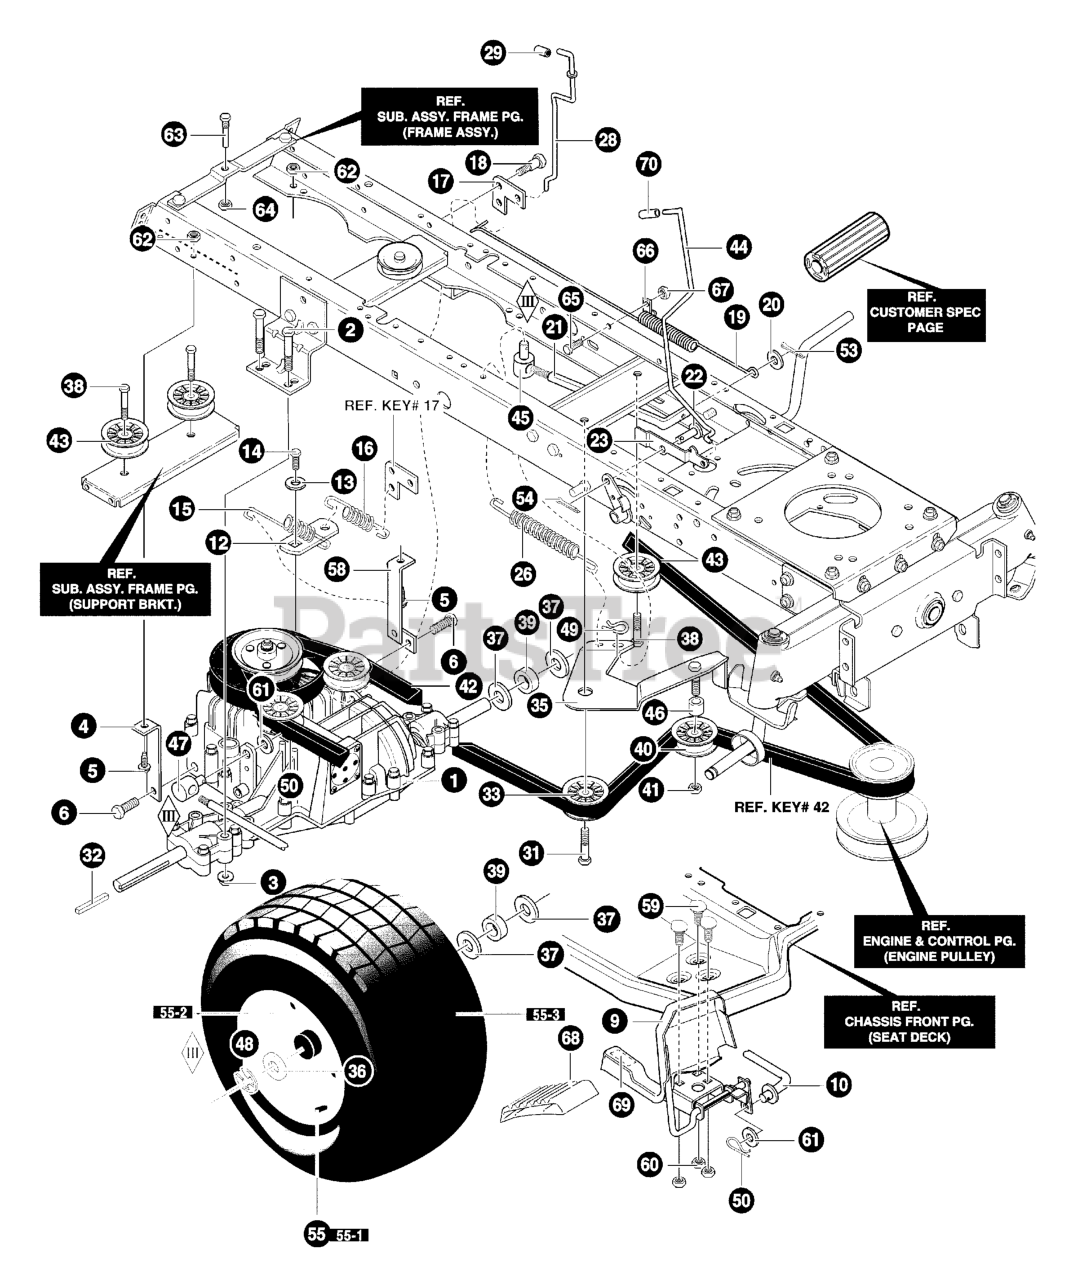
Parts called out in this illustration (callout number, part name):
1	Transaxle, Peerless Hydro **
2	SCREW, 5/16-18 x 2.50
3	NUT, 5/16-18
4	STABILIZER BRACKET
5	SCREW, 5/16-18 x 1.00
6	SCREW, 5/16-18 x 0.75
9	PEDAL ASSY. HYDRO
10	ROD, FOOT CONTROL
12	BRKT, SHIFT
13	WASHER, TRANSAXLE
14	SCREW, 1/4-28X.750
15	SPRING - TRANSAXLE
17	BRACKET, DISCONNECT LEVER
18	BOLT, HHSH 5/16-18
19	SPRING, BRAKE
20	WASHER, FLAT
21	ROD, CLUTCH
22	PIN, CLEVIS
23	ZINC LATCH, PARK BRAKE
26	SPRING, TENSION
28	ROD, DISCONNECT CONTROL
29	GRIP, HYDRO DISCONNECT
31	SCREW, 3/8-16 x 1.25
32	KEY, SQUARE
33	PULLEY, IDLER V4L
35	ASSY., IDLER ARM TRACTION
36	WASHER, FLAT
37	WASHER, FLAT .755ID
38	SCREW, 3/8-16 x 1.25
39	SPACER .87X1.78
40	PULLEY, IDLER 2.75 DIA
41	NUT, 3/8-16
42	BELT, V4L 112.75
43	PULLEY, IDLER
44	PARK BRAKE CONTROL ROD
45	SPACER 1/2 TO 17MM
46	ROD, SHIFT
47	ADJUST NUT 1/2-13
49	PIN, HAIR
50	PIN, HAIR
53	COTTER PIN
54	COTTER PIN
55	TIRE & RIM ASSY
55-1	VALVE STEM
55-3	TIRE 20X8X8
58	ASM., BRACKET STABILIZER
59	BOLT, 5/16-18X.75 CARR.
60	NUT, 5/16-18 HEX
61	WASHER, FLAT
62	NUT, 5/16-18X.75
63	SCREW GUIDE
64	NUT, 5/16-18
65	SCREW, 1/4-20X.50
66	WIRE RETAINER
67	NUT, 1/4-20
68	PEDAL, PAD SANDPAPER
69	PAD, TOE SANDPAPER
70	CAP, DUMP VALVE ROD
